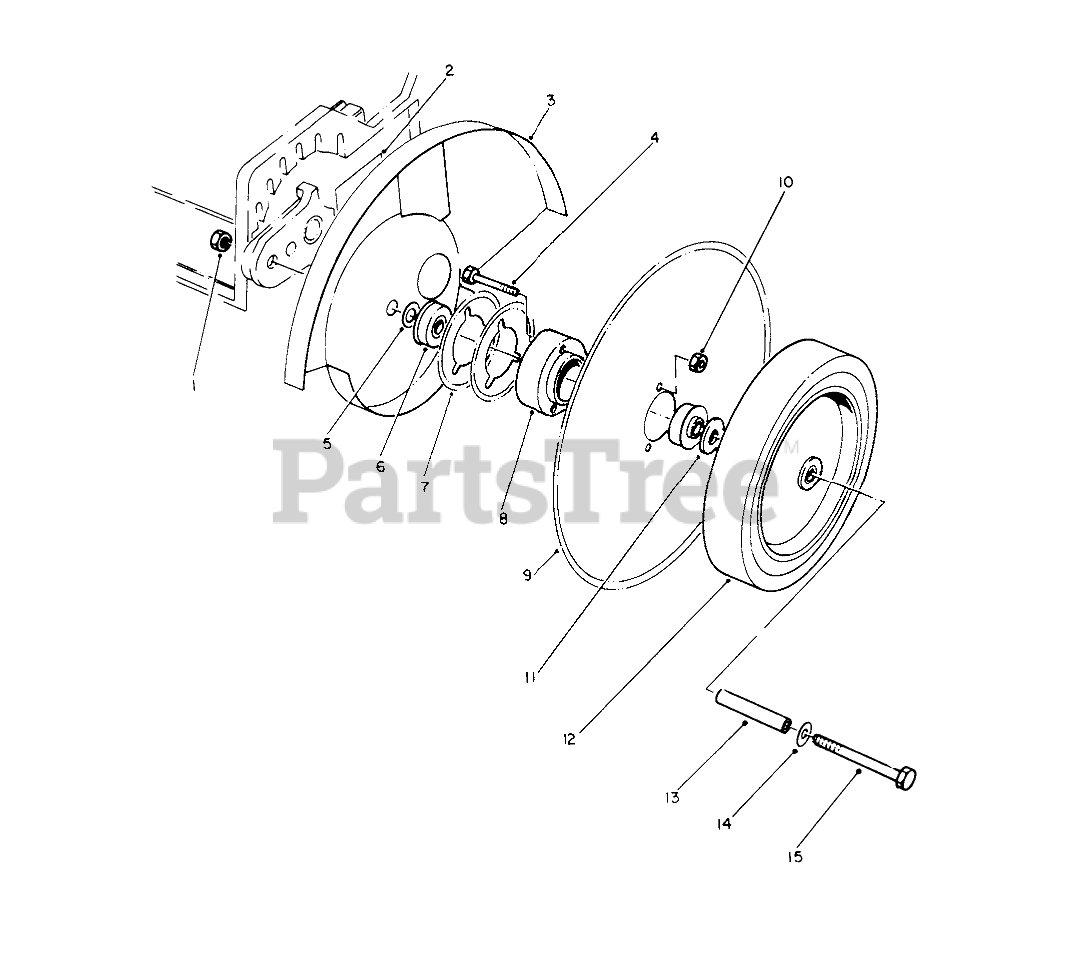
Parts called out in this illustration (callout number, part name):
1	Nut
2	Decal-Toro Edger
3	Shield
4	SCREW-HH
5	WASHER
6	BEARING-BALL
7	Gear-Wheel
8	Spacer-Hub
9	Blade-Edger 80 Tooth
10	NUT-LOCK, SIDE
11	WASHER
12	Wheel Assy. (Incl. Ref. #13)
13	BUSHING
14	Spacer-Wheel Bolt
15	WASHER-FLAT
16	SCREW-HH
